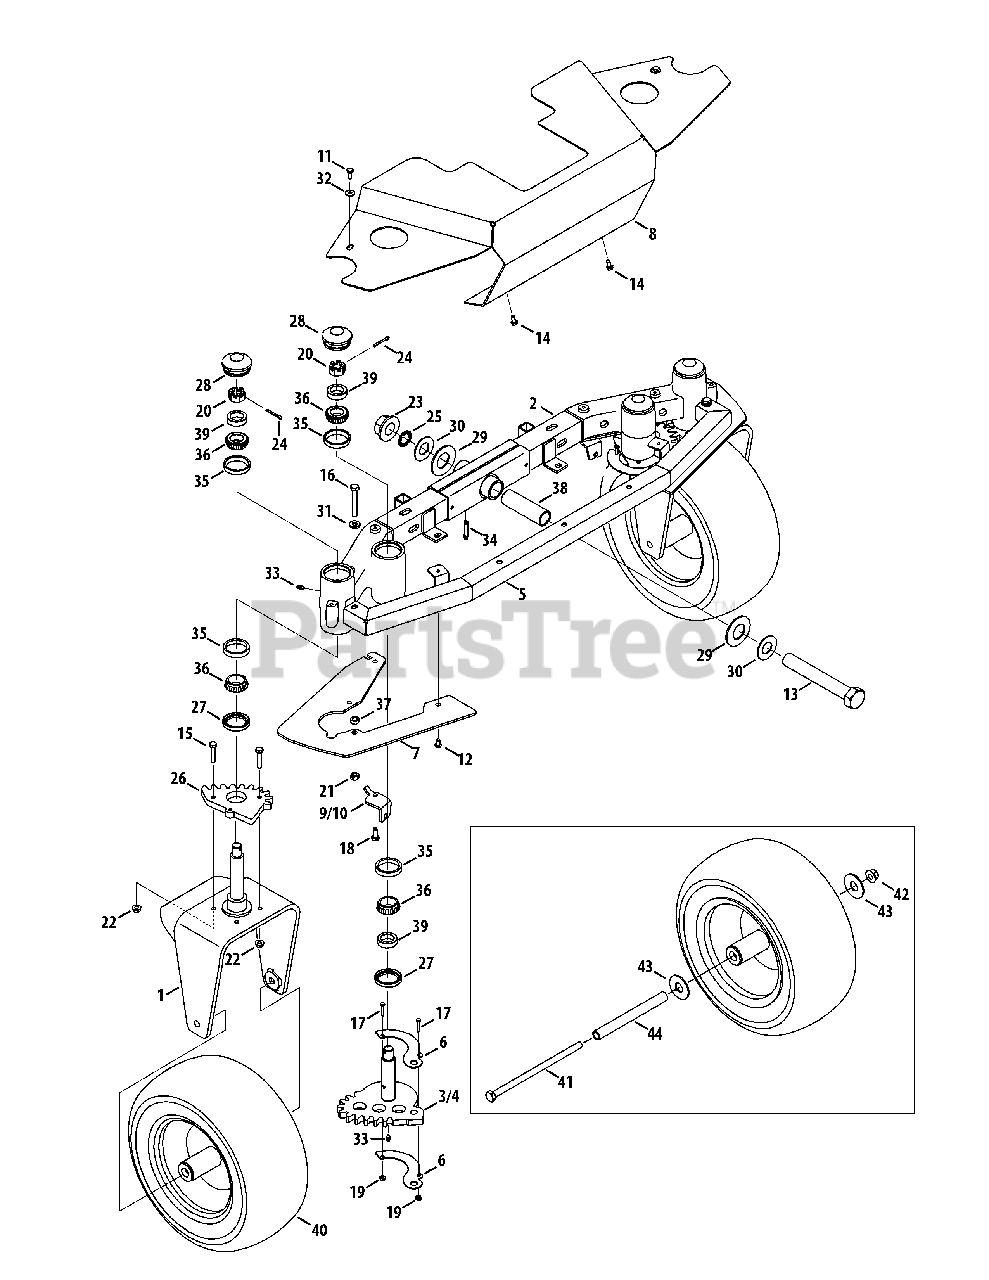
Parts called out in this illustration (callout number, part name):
1	Yoke Assembly
2	Axle Assembly
3	LH Steering Gear
4	RH Steering Gear
6	Gear Cable Mounting Bracket
7	Gear Panel Cover
11	Hex Cap Screw, 1/4-20 x .625
12	Screw, 1/4-20 x .5
13	Hex Cap Screw, 1-14 x 7.0
14	Hex Flange Screw, 1/4-20 x .500
15	Hex Cap Screw, 5/16-18 x 1.50
16	Hex Cap Screw, 3/8-16 x 2.50
17	Machine Screw, #10-24 x 1.00
18	Hex Cap Screw, 5/16-18 x .75
19	Nut, #10-24, Hexlock
20	Nut, 3/4-16, Slotted
21	Nut, 3/8-16, Hexlock
22	Nut, 5/16-18, Flangelock
23	Nut, 1.0-14, Flangelock
24	Cotter Pin, 5/32 x 1.25
25	Retainer Ring
26	Steering Gear
28	Axle Grease Cap
29	Bell Washer, 1.25 x 2.50 x .180
30	Washer, 1.00 x 2.00 x .075
31	Washer, .407 x .812 x .135
32	Washer, .260 x .720 x .060
33	Grease Fitting, 1/4-28
34	Grease Fitting, 1 39/64
35	Cup Bearing
36	Cone Bearing
37	Spacer, .380 x .625 x .265
38	Spacer, 1.005 x 1.247 x 4.1
39	Spacer, 1.00 x 1.50 x .437
40	Wheel Assembly, 15 x 6.5-8
41	Hex Cap Screw, 1/2-13 x 9.5
42	Nut, 1/2-13, Flangelock
43	Washer, .781 x 2.00 x .105
44	Spacer, .51 x .750 x 7.38
